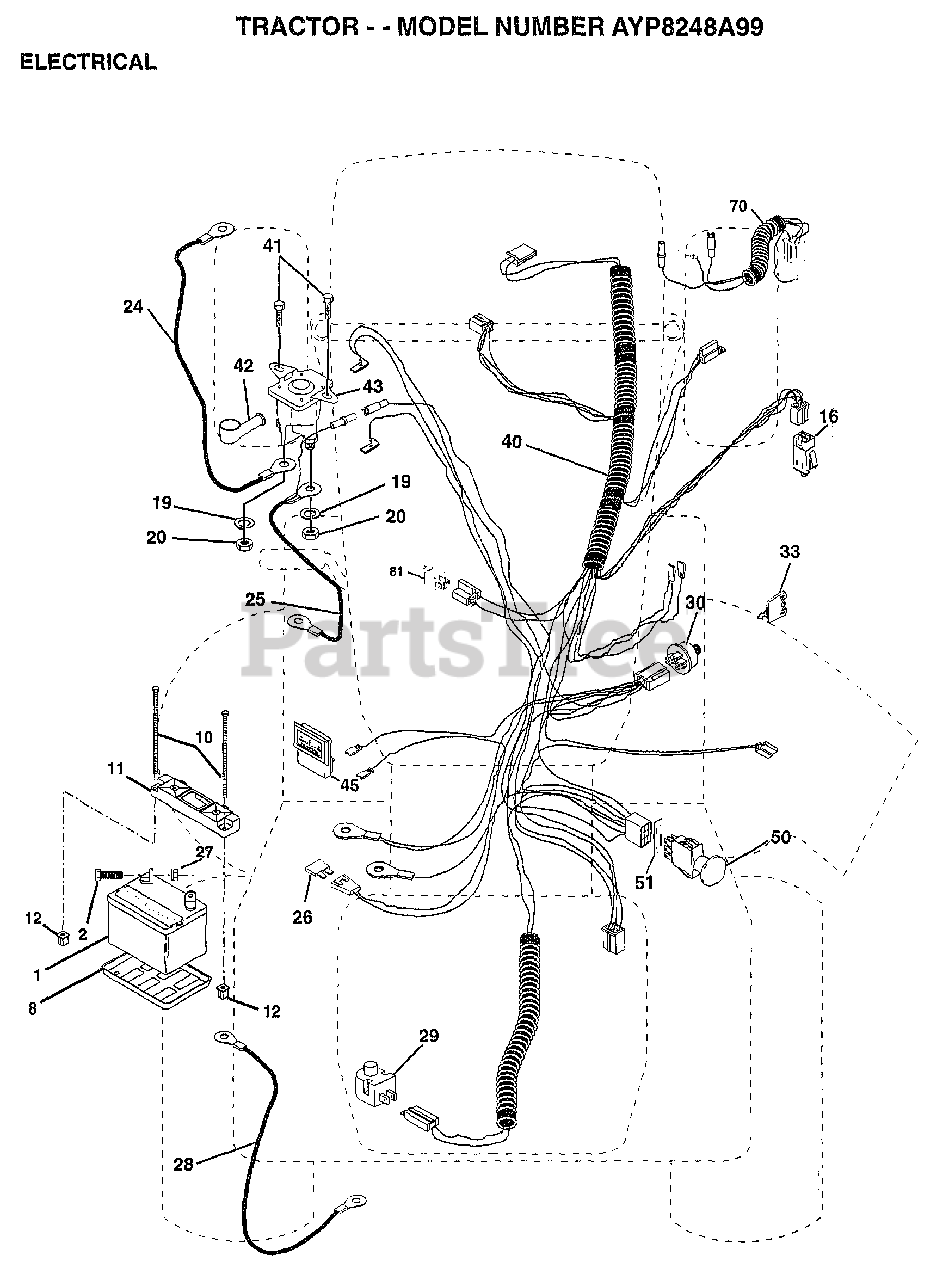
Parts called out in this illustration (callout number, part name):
2	BOLT LT
8	"TRAY T, BATTERY"
11	HOLDDOWN BATTERY
16	SWITCH INTERLOCK
20	NUT
21	HARNESS.ASM.LIGHT W/4152J
22	HEADLAMP BULB
24	CABLE-BATTERY T
25	CABLE.6GA.12.5.
26	FUSE HYT
27	NUT
28	CABLE T
29	SWITCH.PLUNGER
30	SWITCH.IGN.
33	KEY MLD GEN DELTA
40	HARNESS.IGNITION
41	SCREW
45	AMMETER
50	PTO SWITCH.BLK
51	RING RETAIN PTO
70	HARNESS.ENGINE
81	RELAY ASSY T
